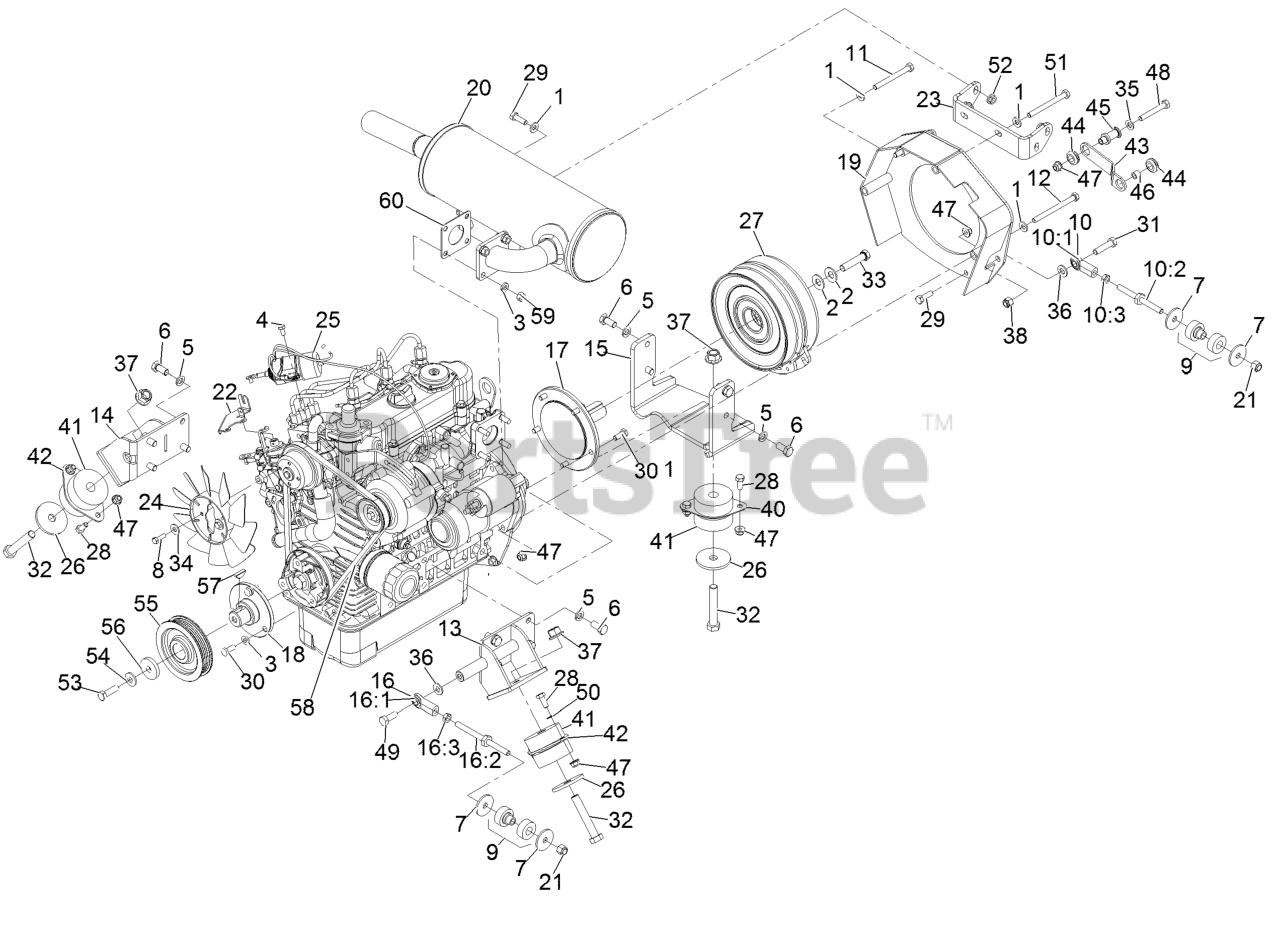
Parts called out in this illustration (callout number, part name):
1	WASHER-SPRING
2	WASHER-SPRING
3	WASHER-LOCK
4	SCREW-HH
5	Washer-Lock M10
6	SCREW-CAP
8	SCREW-HH
9	ISOLATOR-LINK
10	BALL JOINT LINK ASM
10:1	JOINT-BALL, END
10:2	LINK,REAR A-T AXIAL
10:3	NUT-HJ
11	SCREW-HH
12	SCREW-HH
13	ENGINE MOUNT-LH
14	ENGINE MOUNT-RH
15	BRACKET,ENGINE MOUNT
16	ASM, A-T LINK
16:1	JOINT-BALL, END
16:2	LINK,REAR A-T AXIAL
16:3	NUT-HJ
17	SHAFT,KUBOTA 902 STUB
18	HUB,PUMP DRIVE
19	WLD,FLYWHEEL COVER
20	MUFFLER KIT - KUBOTA
21	NUT-LOCK
22	BRACKET, KD THROTTLE
23	SUPPORT-MUFFLER
24	FAN,COOLING 7"
25	SOLENOID,FUEL
28	SCREW-HH
29	SCREW-HH
30	SCREW-HH
31	SCREW-HH
32	SCREW-HH
33	SCREW-HH
34	WASHER-FLAT
35	WASHER-PLAIN
36	WASHER-FLAT
37	Nut-Lock 1/2-13
38	NUT-LOCK, NI
40	FLANGE ASM
41	ISOLATOR,ENGINE
42	FLANGE-11GA
43	CLUTCH LINK
44	GROMMET
45	CLUTCH STANDOFF
47	NUT-HF, NI
48	SCREW-HH
49	SCREW-HH, LOCK
50	WASHER-LOCK
51	SCREW-HH
53	SCREW-HH
54	WASHER-BELLEVILLE
55	SHEAVE,5K 4"PD POLY-V
56	WASHER-CLUTCH
57	KEY-WOODRUFF
58	BELT,KUBOTA 902 ALT
59	NUT-HEX
60	GASKET-MUFFLER
